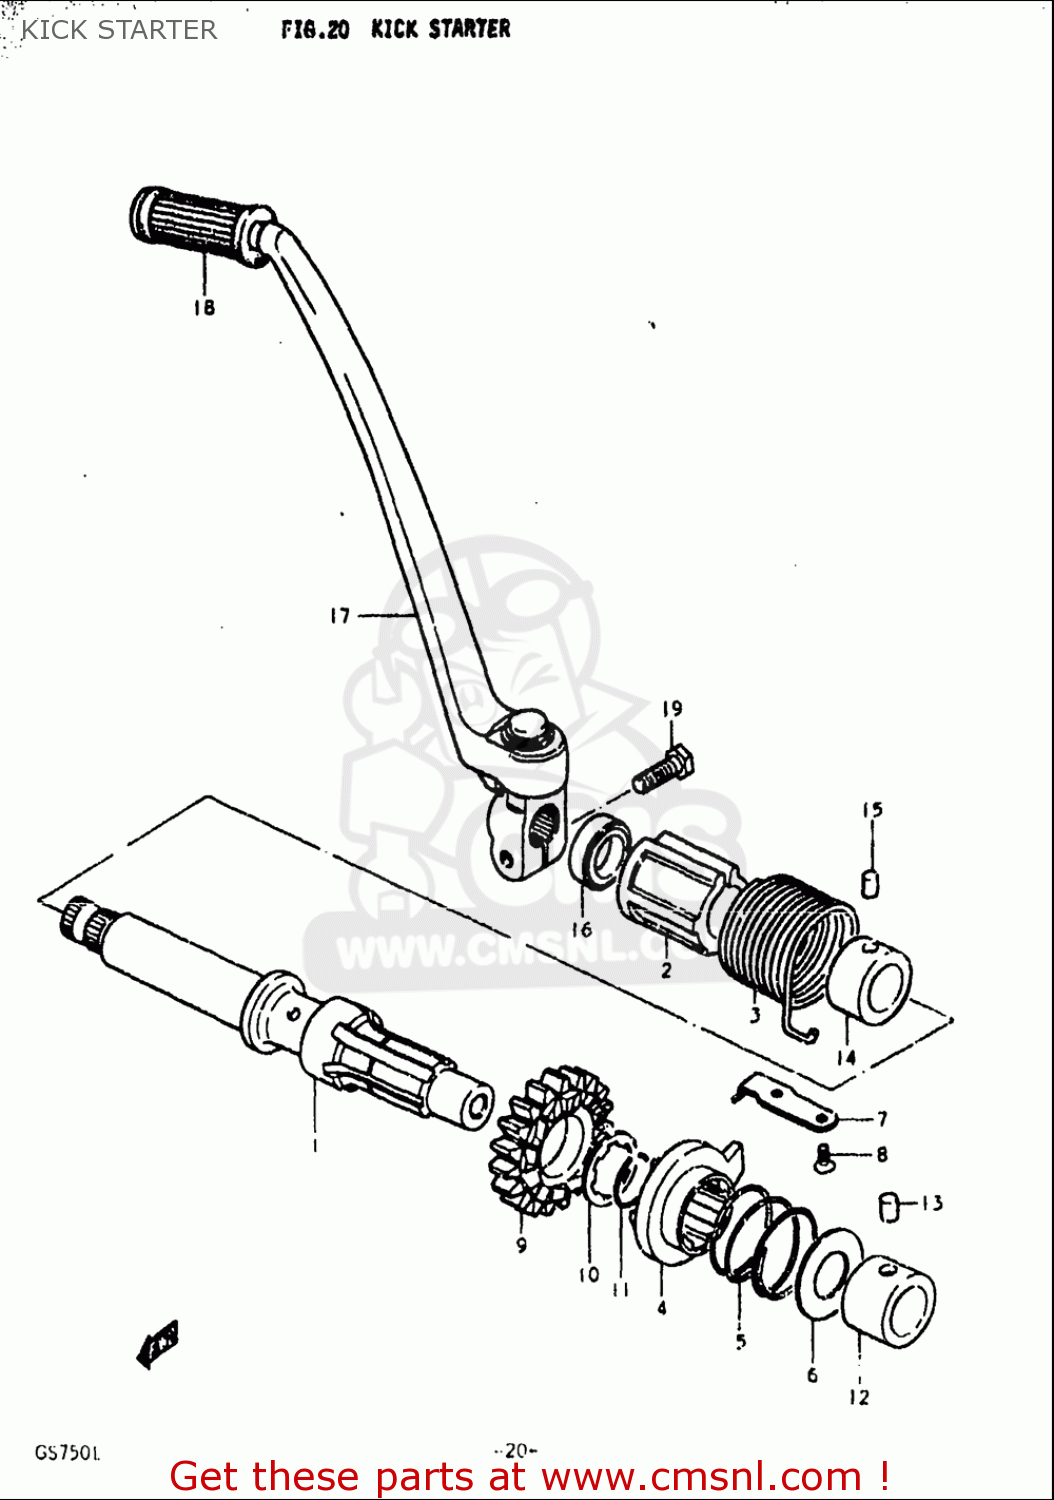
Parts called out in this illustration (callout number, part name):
3	SPRING
4	STARTER,KICK
5	SPRING
8	SCREW
9	GEAR,KICK STARTER DRIVE
10	WASHER,LOCK
11	CIRCLIP
13	PIN
15	PIN
16	SEAL,OIL(20X27X5)
17	LEVER ASSEMBLY,KICK STARTER
18	RUBBER,KICK STARTER PEDAL
19	BOLT
